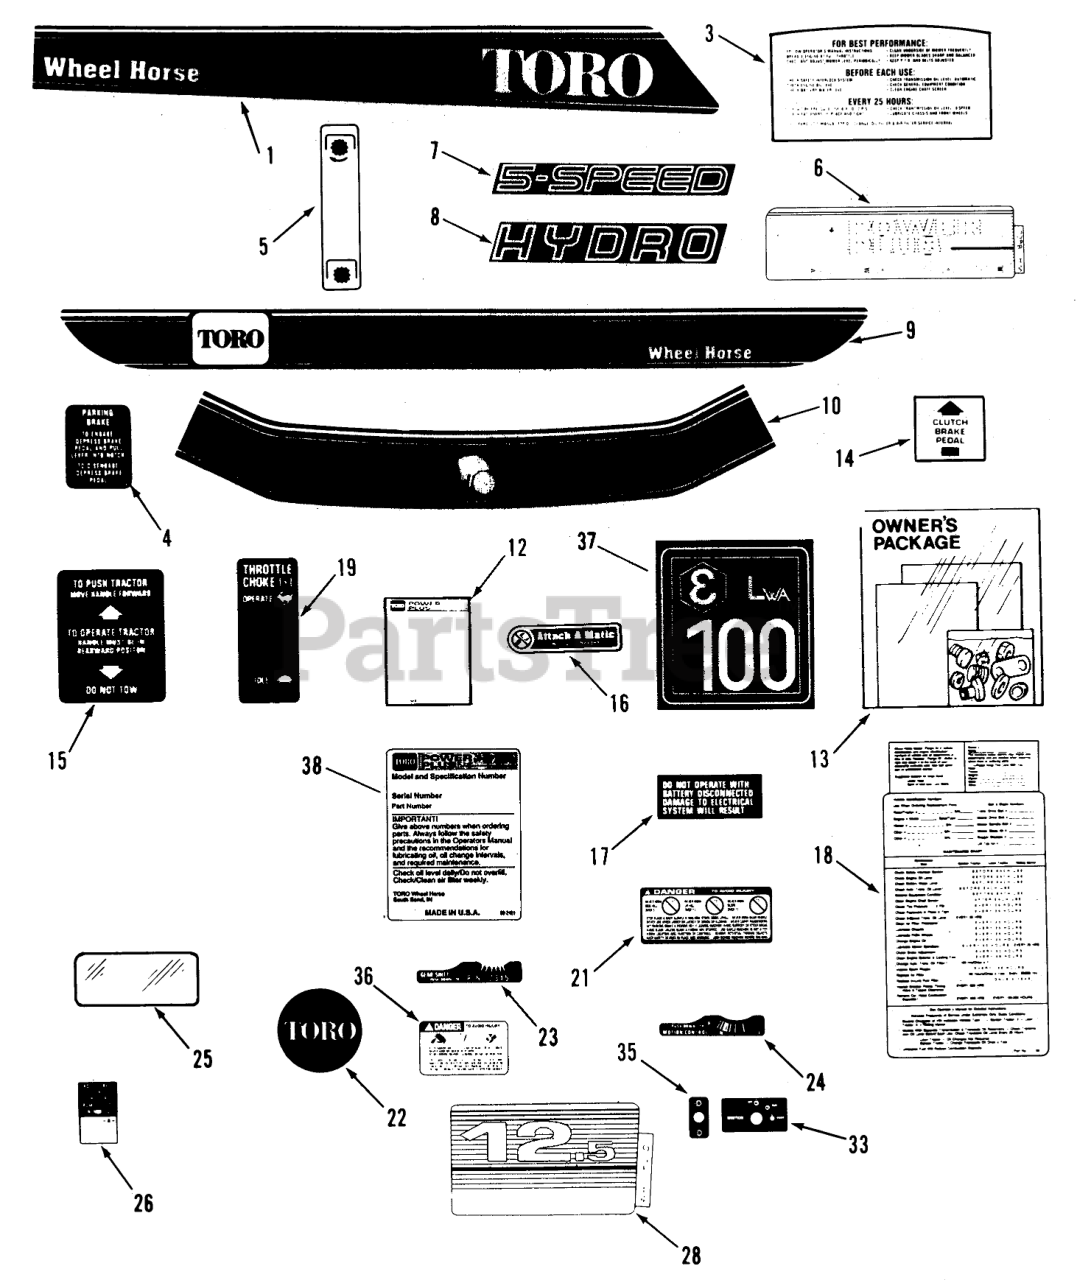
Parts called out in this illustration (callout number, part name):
1	DECAL-HOOD 212-5 R H
3	Decal-Hood Rear
4	DECAL PARKING BRAKE
5	DECAL-PTO
6	DECAL-PWR PLUS
7	DECAL-MODEL 5-SPEED
8	DECAL-MODEL HYDRO
9	DECAL-FENDER
10	DECAL-FRONT HOOD
14	DECAL CLUTCH & BRAKE
15	DECAL-PUSH
16	Decal-Attach-A-Matic
17	DECAL ELECT SYSTEM
18	MAINTENANCE-DECAL
19	DECAL-THROTTLE
21	DECAL-DANGER
22	DECAL-TORO ENGINE
23	DECAL-SHIFT 5-SPEED
24	DECAL-MOTION CONTROL
25	DECAL-OVERLAY
26	DECAL-PTO BELT ADJ
28	DECAL-PWR PLUS 12.5
33	DECAL-IGNITION
35	DECAL-LIGHTS
37	DECAL-EUROPE
38	Decal-Engine Spec.
